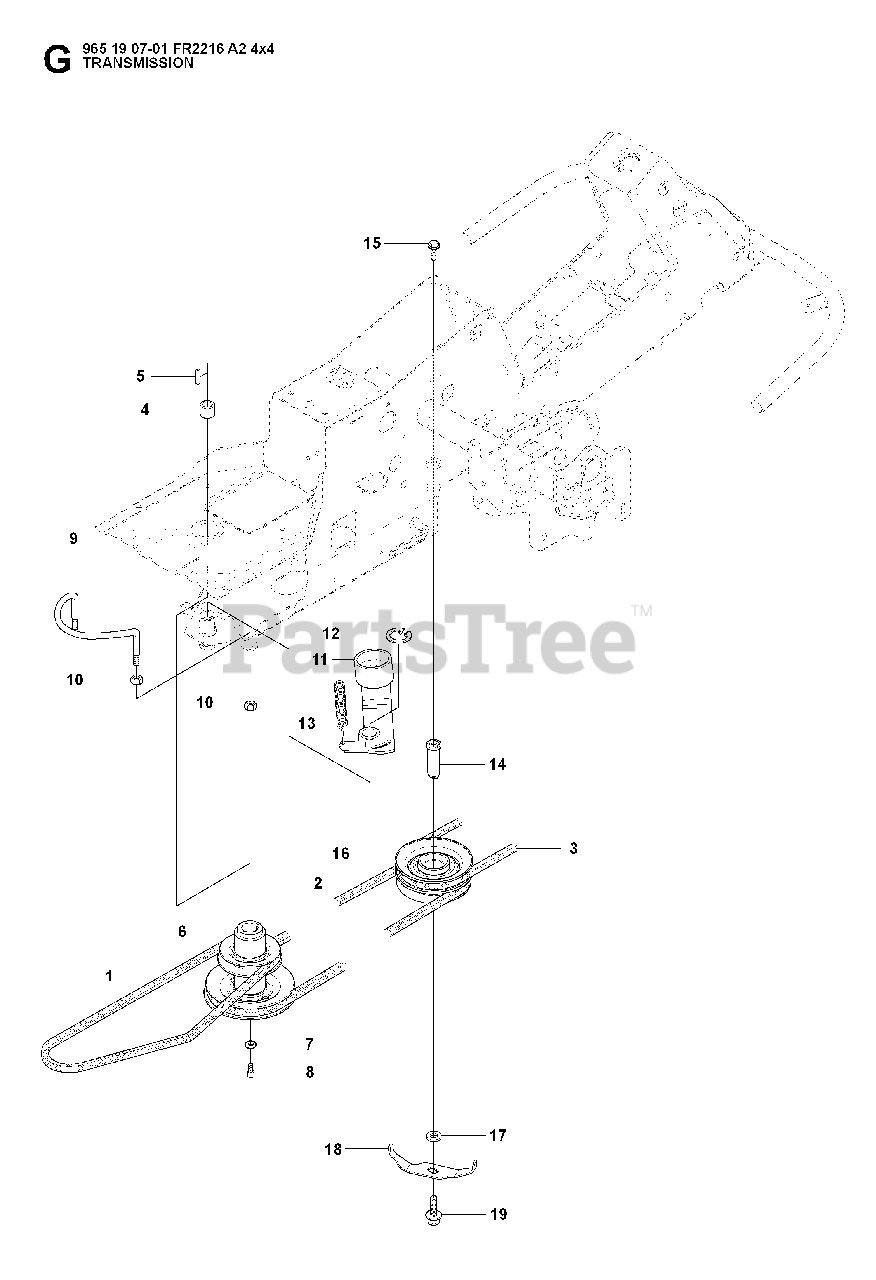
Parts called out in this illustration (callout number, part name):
2	BELT
3	BELT
9	BELT GUIDE
11	TENSIONER
12	RETAINING RING SGA 25
14	SHAFT
18	BELT GUIDE
19	BOLT
